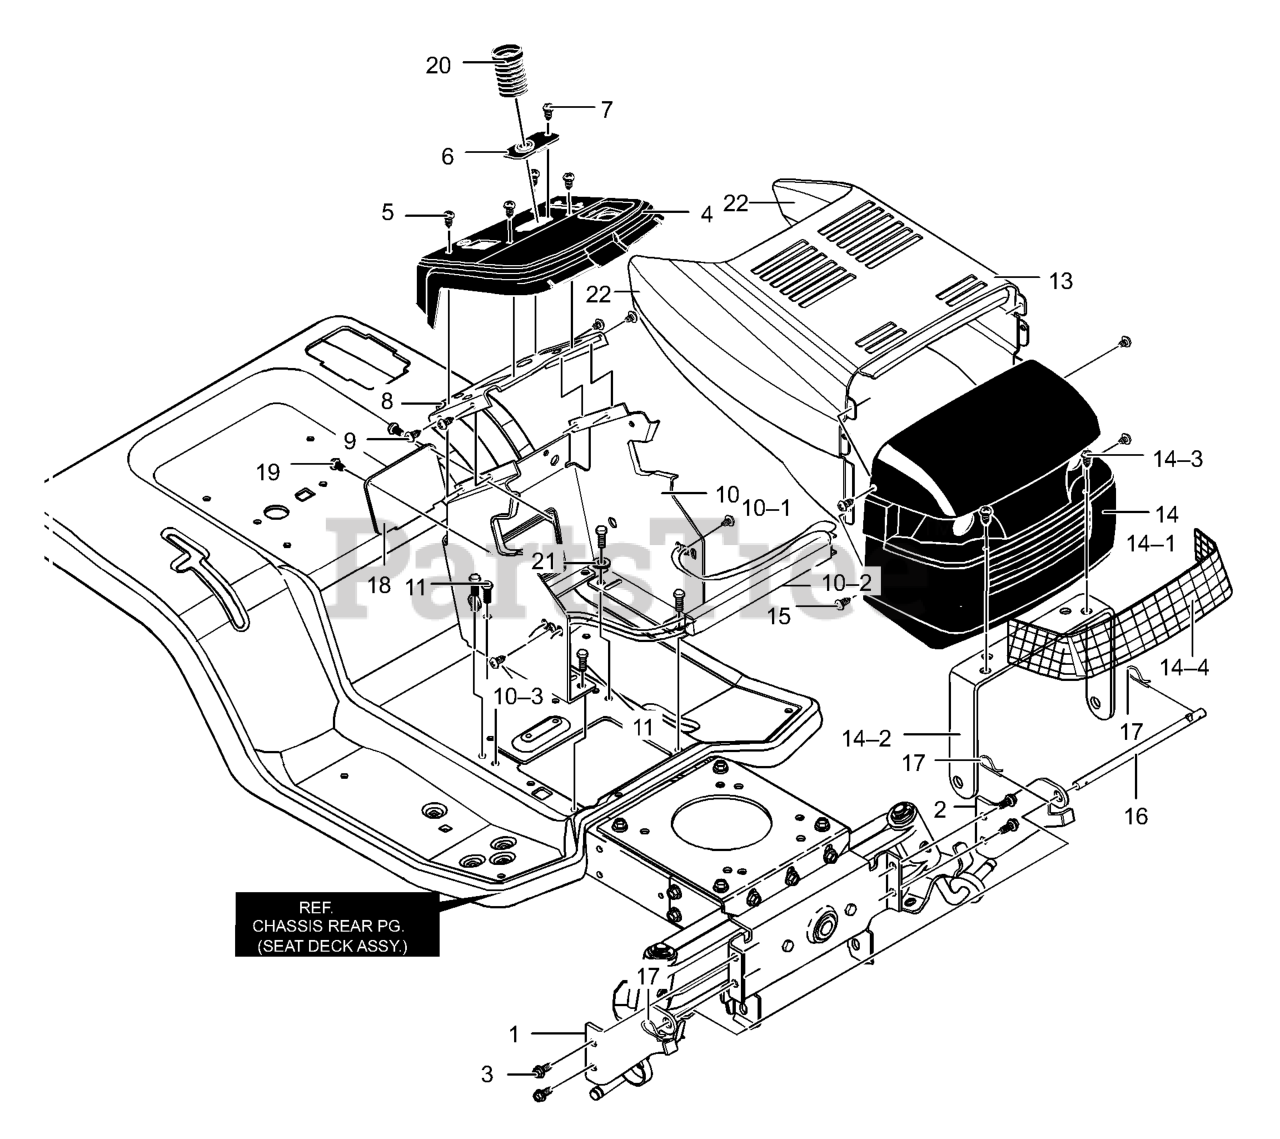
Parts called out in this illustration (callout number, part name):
1	BRACKET, RIGHT GRILLE RH
2	BRACKET, LEFT GRILLE
3	SCREW 5/16-18X.75
5	SCREW, 10-24X.500
6	BEARING, UPPER
7	SCREW 1/4-14X.50
8	PLATE, DASH
9	SCREW, 10-24X.500
10	ASSEMBLY, CONSOLE
10-1	SUPPORT, DASH
10-2	CHANNEL, SUPPORT
11	SCREW 5/16-18X.75
14	ASSEMBLY, GRILLE
14-1	GRILLE
14-3	BRACE, HOOD
16	ROD, HOOD PIVOT
17	PIN, HAIR
18	PANEL, ACCESS
19	SCREW, 10-24X.500
20	BELLOWS, STEERING POST
21	WASHER
